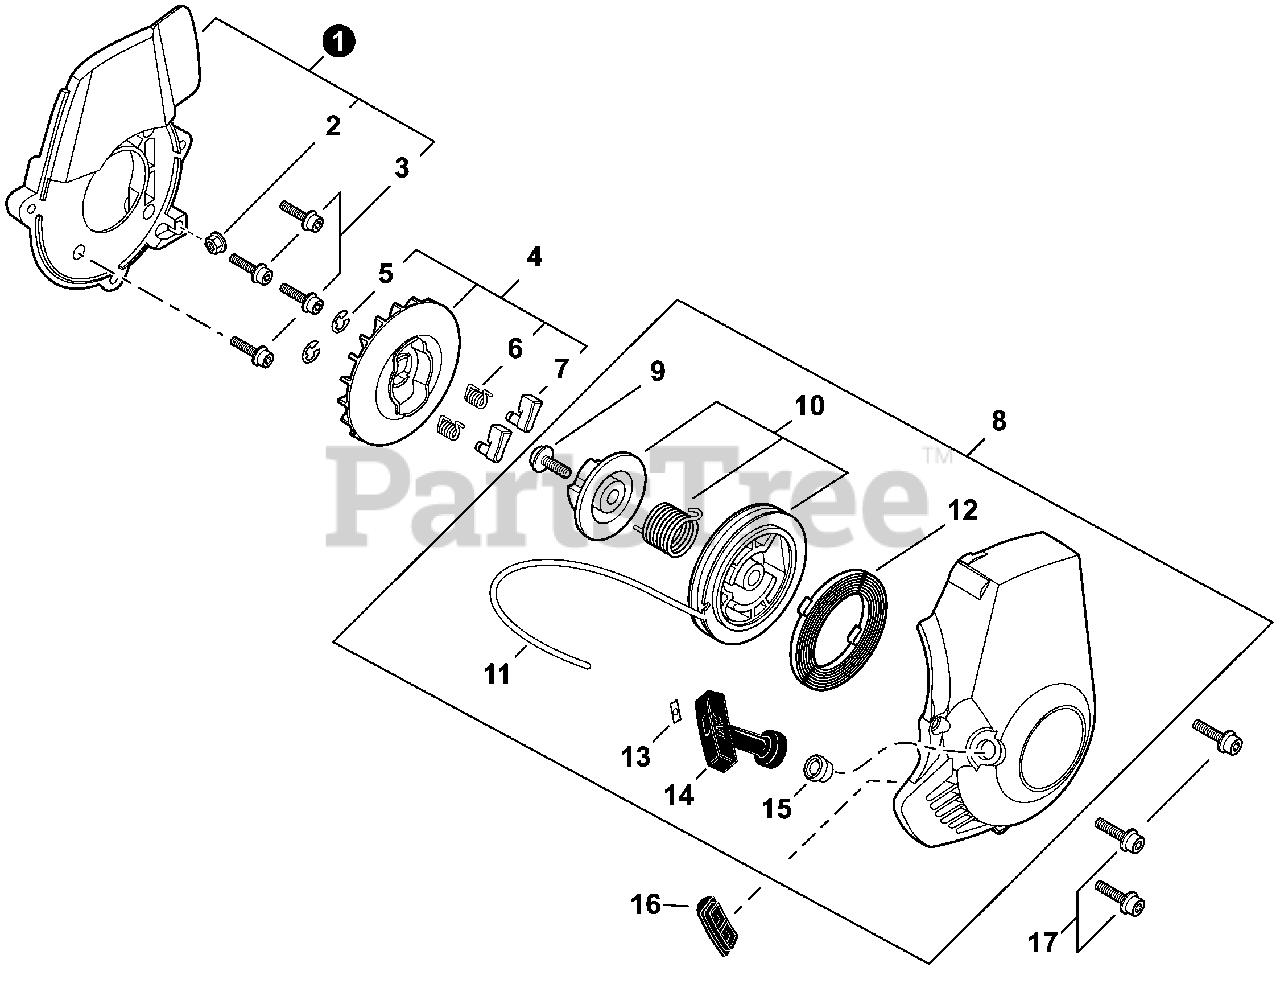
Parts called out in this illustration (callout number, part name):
1	SPACER ASSY.
2	NUT, FLANGE M5
3	BOLT 4×16
4	PAWL ASSY, STARTER
5	E-RING 4
6	SPRING, RETURN
7	PAWL, STARTER
8	STARTER, RECOIL
9	SCREW 5
10	REEL/CAM PLATE SET
11	ROPE, STARTER 3×700
12	SPRING, RECOIL
13	RETAINER, ROPE
14	GRIP, STARTER
15	GUIDE, ROPE
16	CUSHION
17	BOLT 5×14
